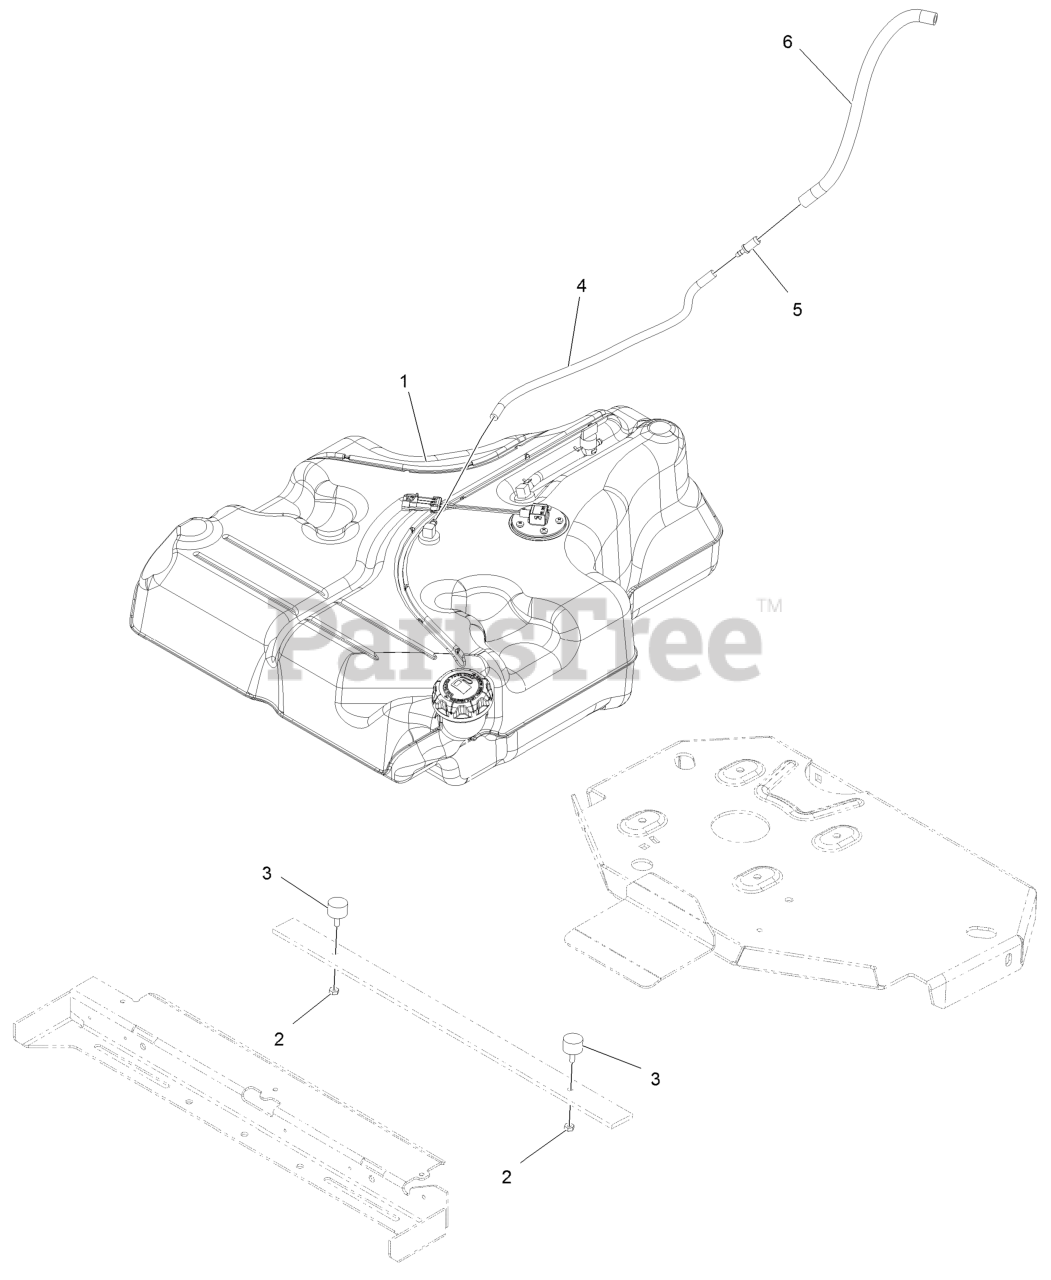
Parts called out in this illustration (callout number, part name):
1	Fuel Tank ASM
2	Nut-Jam 1/4-20
3	Bumper-Rubber (W/ Stud)
4	Hose-Fuel
5	Fitting-Straight
6	Hose-Fuel
